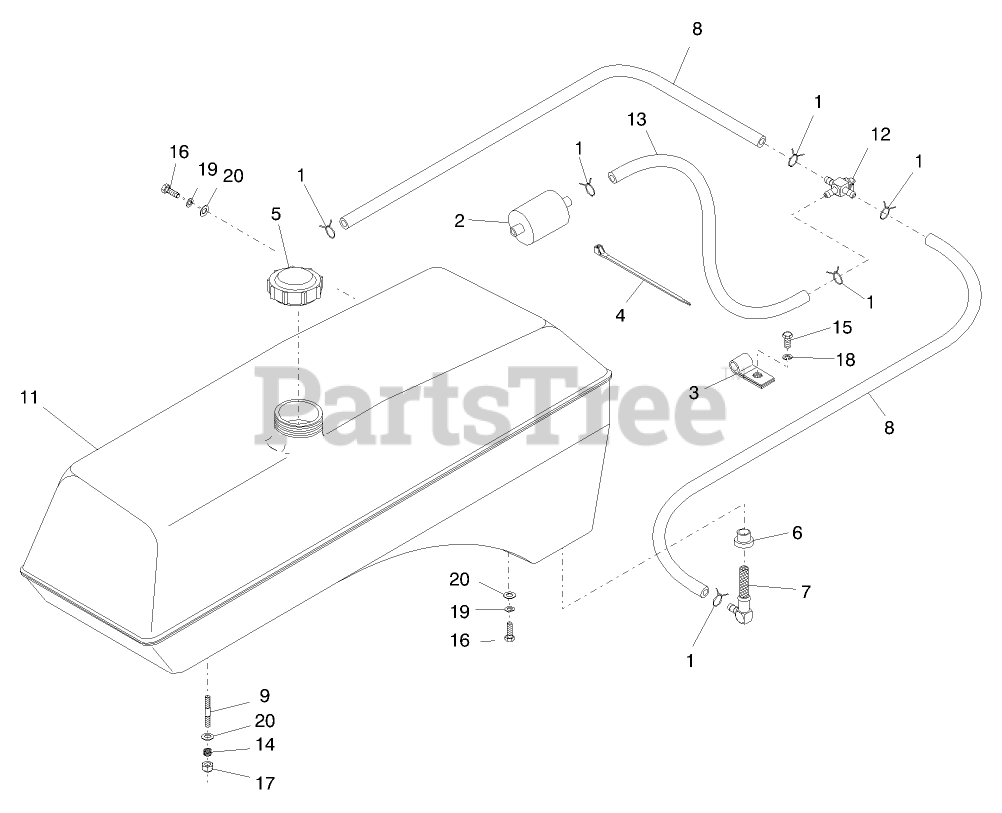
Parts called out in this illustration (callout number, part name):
1	Clamp
2	Filter-Fuel
3	Clip
4	Tie-Plastic
5	Cap-Fuel Tank
6	Bushing
7	Elbow
8	Fuel Line
9	Stud
10	Tank-Fuel LH
11	Tank-Fuel RH
12	Valve-Fuel Line
13	Fuel Line
14	Spring-Fuel Tank
15	SCREW-HH
16	SCREW-HH
17	Nut-Lock
18	WASHER-LOCK
19	WASHER-LOCK
20	WASHER-FLAT
